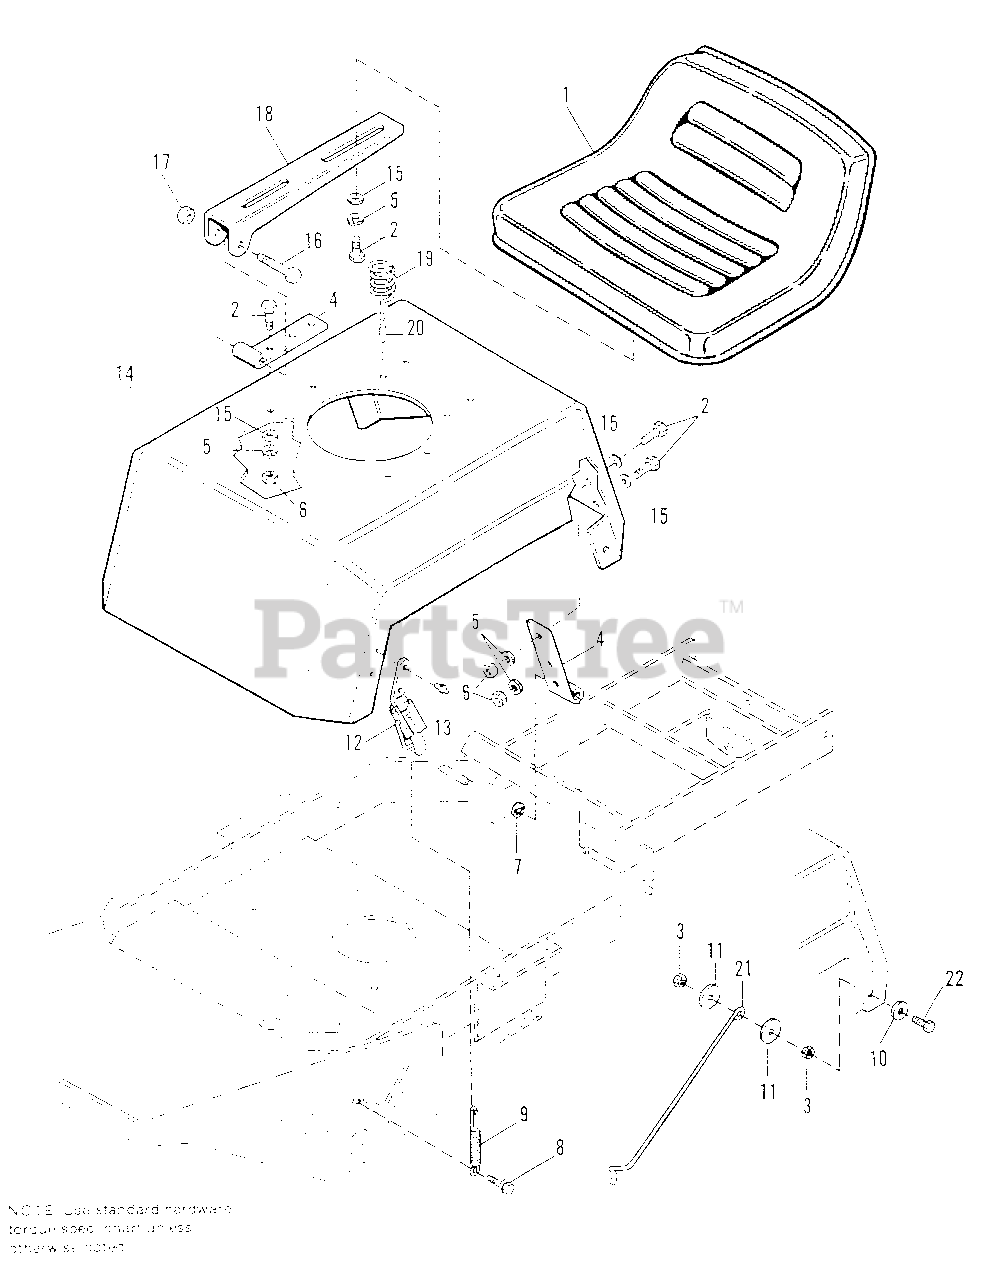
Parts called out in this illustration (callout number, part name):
2	CAPSCREW, 5/16-18 x 3/4
3	NUT, Hex Centerlock, 1/4-20
4	HINGE, Seat Deck
5	LOCKWASHER, 5/16
6	NUT, Hex, 5/16-18
7	RING, Retaining
8	SCREW, Taptite, 5/16-18 x 1/2
9	SPRING, Latch
10	WASHER, 1/4 x 3/4
11	WASHER, 1/4 x 1-1/4
12	LATCH, Seat, Pull Tight
13	RIVET, Seat Latch
15	WASHER, Flat, 5/16
16	CAPSCREW, 3/8-16 x 2
17	NUT, Hex Lock, 3/8-16
18	HINGE, Upper, Seat
19	SPRING, Seat
20	COVER, Spring
21	ROD, Seat Deck
22	CAPSCREW, Hex, 1/4-20 x 1
